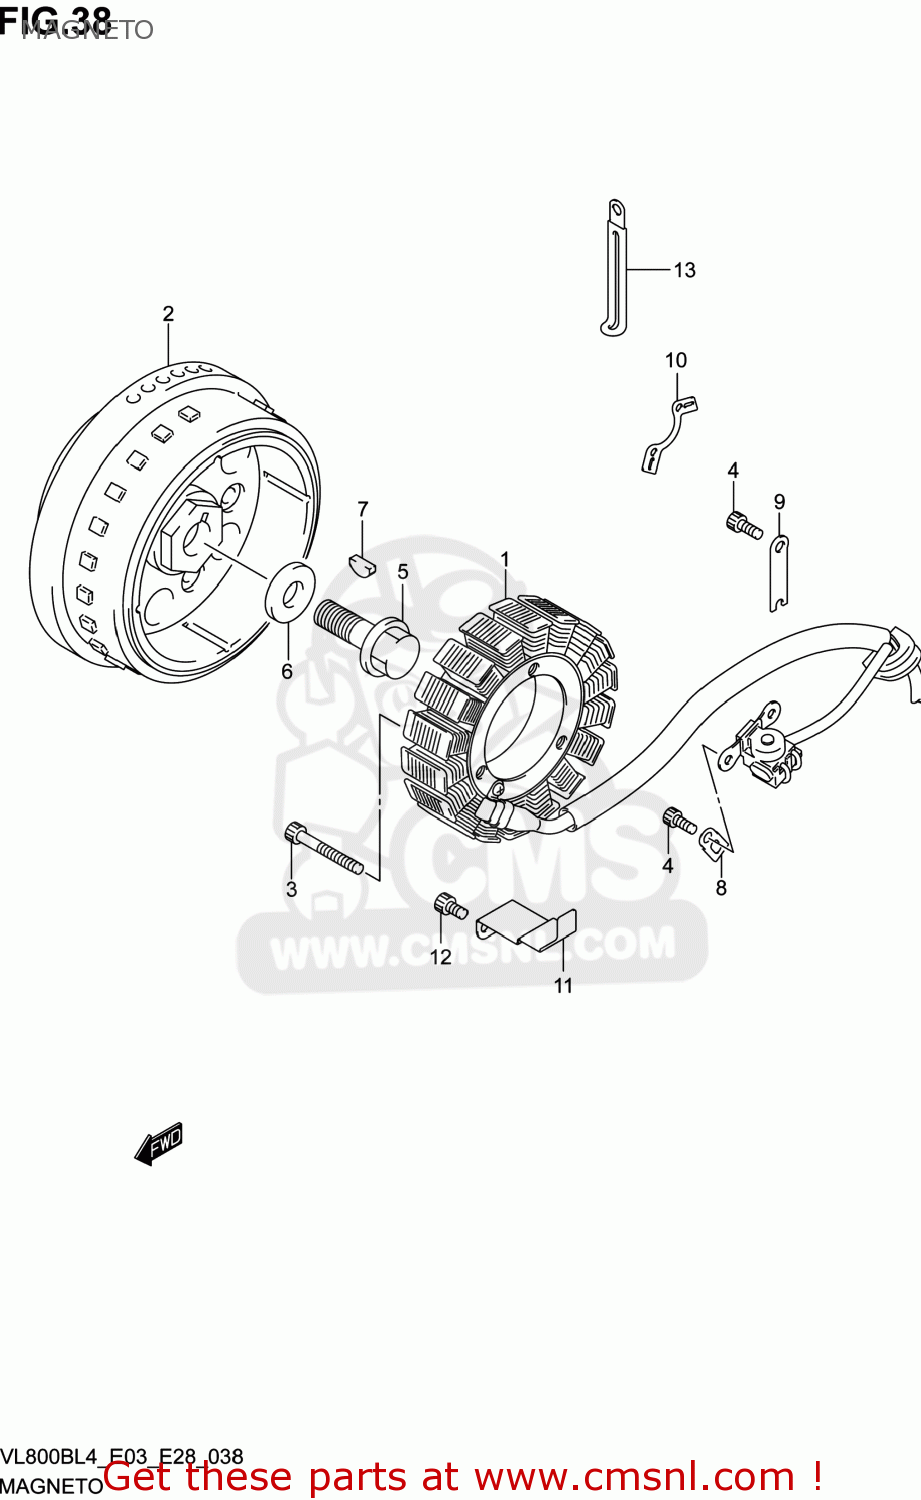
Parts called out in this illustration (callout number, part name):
1	STARTER ASSY
2	ROTOR ASSY
3	BOLT
4	BOLT
5	BOLT(14X43)
6	WASHER(14X29X4)
7	KEY
8	CLAMP,GENERATOR LEAD WIRE
9	CLAMP NO.1,MAGNETO READ WIRE
10	CLAMP,MAGNETO LEAD
11	CLAMP,MAGNETO LEAD WIRE
12	BOLT
13	CLAMP(L:80)
